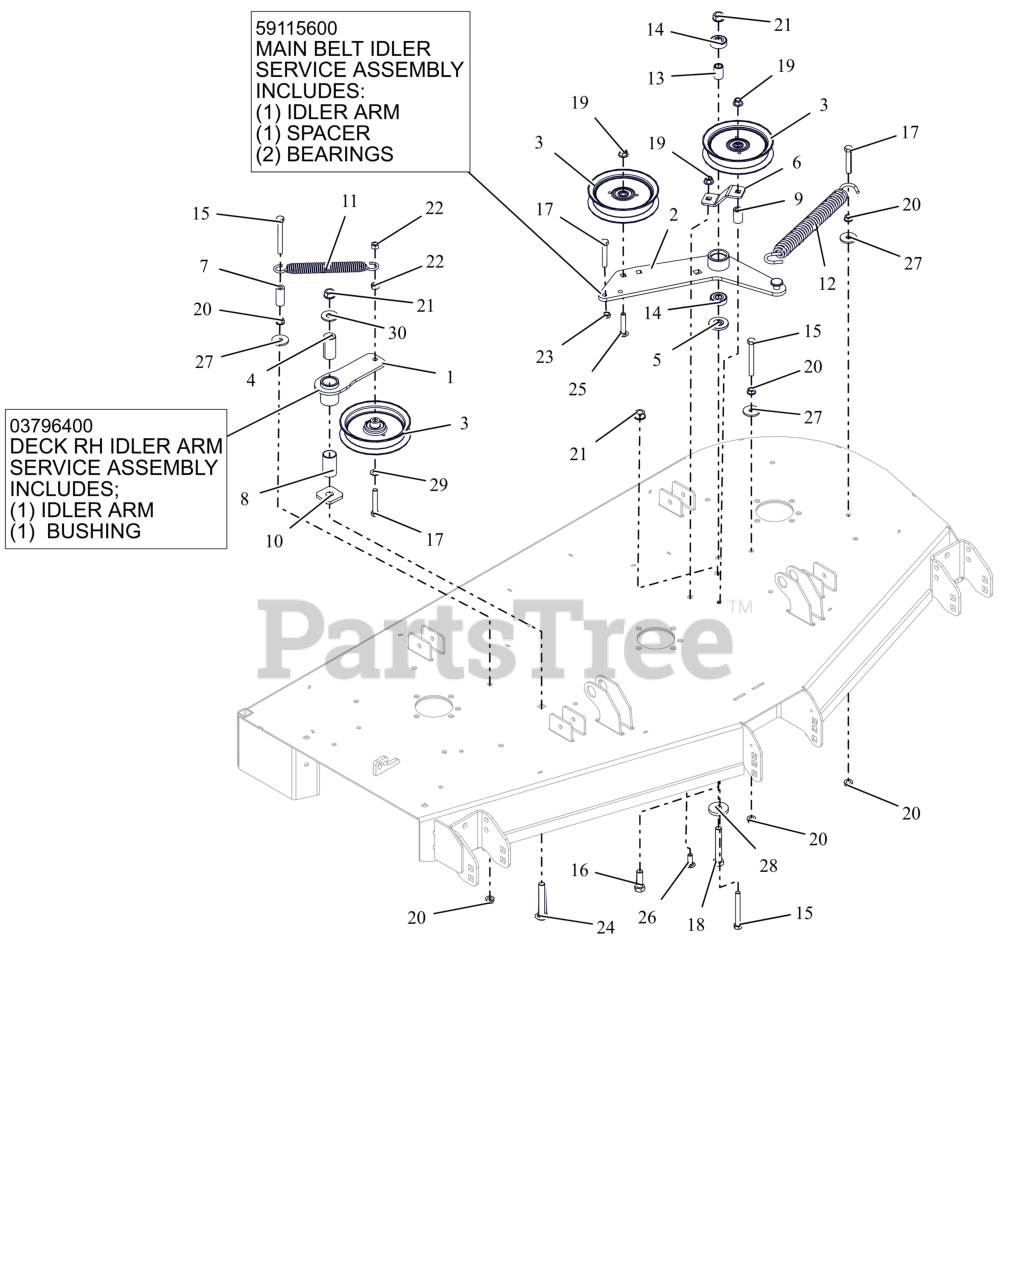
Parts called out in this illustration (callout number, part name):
1	WMT, IDLER ARM - BLACK
2	WLDMT, DECK PTO IDLR ARM
3	IDLER, FLAT 5.00"
4	BSHG, SPCR .502X.997X2.03 PM
5	SPACER, IDLER ARM
6	PTO FIXED IDLER MTG BRKT -RED
7	HOSE, .38 X 1.65
8	BSHG, 1.00X1.125X1.937
9	BUSHING, SLV .380X.750X1.190
10	WSHR-FLT .640X1.75X.250
11	SPRING, EXTENSION
12	SPRING, EXTENSION
13	SPACER .510 X .75 X 1.1485
14	BRG-BALL .500X1.38X.437
15	BLT, HEX .38-16X3.25 G5 ZCC
16	BLT,HEX .50-13X1.50 G5 ZCC
17	BLT,HEX .38-16X2.25 G5 ZCC
18	BLT,HEX .50-13X3.25 G5 ZCC
19	NUT,NYL-FLG .38-16 GF ZCC
20	NUT, SPNLK-FLG .38-16 G5 ZCC
21	NUT-LK-CTR-FLG .500-13 GG ZCC
22	NUT-LK-CTR .38-16 ZC120
23	NUT-JAM .375-16 G2 ZCC
24	BTL,RHSSN .500-13 X 3.25 G5 ZCC
25	BLT,RHSSN.375-16X2.00 G5 ZCC
26	BLT,RHSSN .38-16X1.00 G5 ZCC
27	WSHR,FLT .406X1.375X.135 ZCC
28	WSHR-FL-STL 0.557X1.625X0.25 ZCC
29	WSHR,FLT .406X.812X.065 ZCC
30	WSHR,FLT .563X1.375X.109 ZCC
